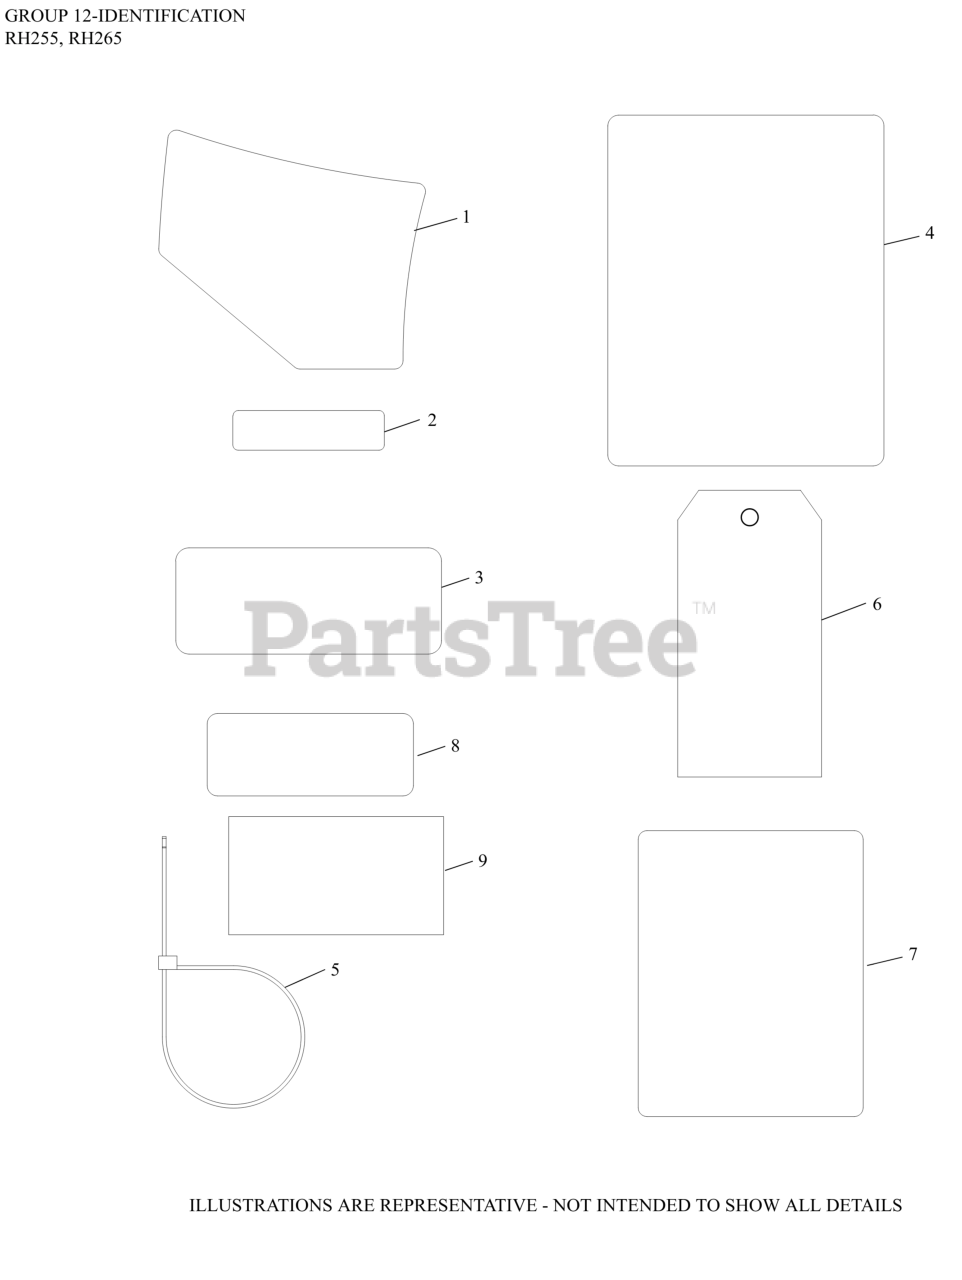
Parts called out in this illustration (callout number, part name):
1	LABEL, HORSEPOWER
2	LABEL STOP/LOW SPEED/HIGH SPEED/CHOKE
6	TAG, HANG
7	LABEL, CLEAR LAMINATION
8	LABEL, CANADIAN COMPLIANCE
